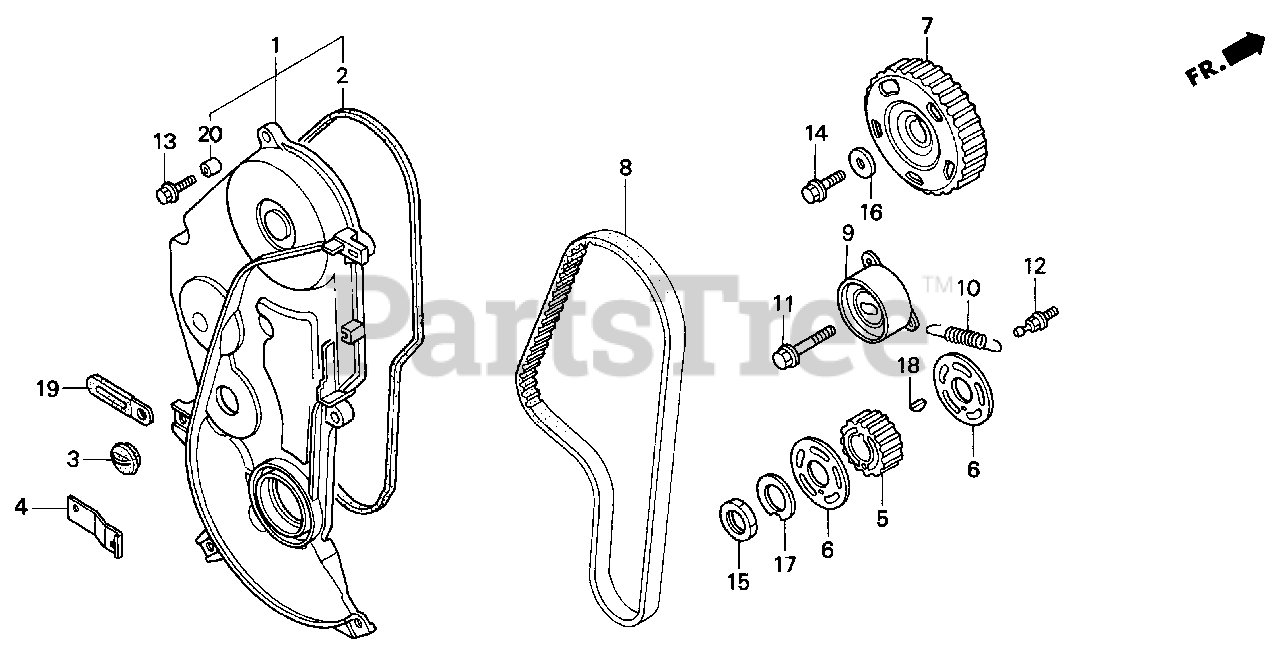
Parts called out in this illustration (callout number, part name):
1	COVER, TIMING BELT
2	GASKET, TIMING BELT COVER
3	GROMMET, TIMING BELT COVER
4	STAY, CABLE HOLDER
5	PULLEY, TIMING BELT DRIVE
6	PLATE, TIMING BELT GUIDE
7	PULLEY, TIMING BELT DRIVEN
8	BELT, TIMING
9	TENSIONER, TIMING BELT
10	SPRING, TIMING BELT ADJUSTING
11	BOLT A, TENSIONER
12	BOLT, TIMING BELT ADJUSTER SPRING (NAGOYA RASHI)
13	BOLT, FLANGE (6X20) (CT200)
14	BOLT, FLANGE (8X22)
15	NUT, LOCK (27MM)
16	WASHER, SPECIAL (28X8.5X4.0)
17	WASHER, LOCK (6MM)
18	KEY, SPECIAL (16X15)
19	CLIP, WIRE HARNESS
20	COLLAR, CONTROL LEVER
